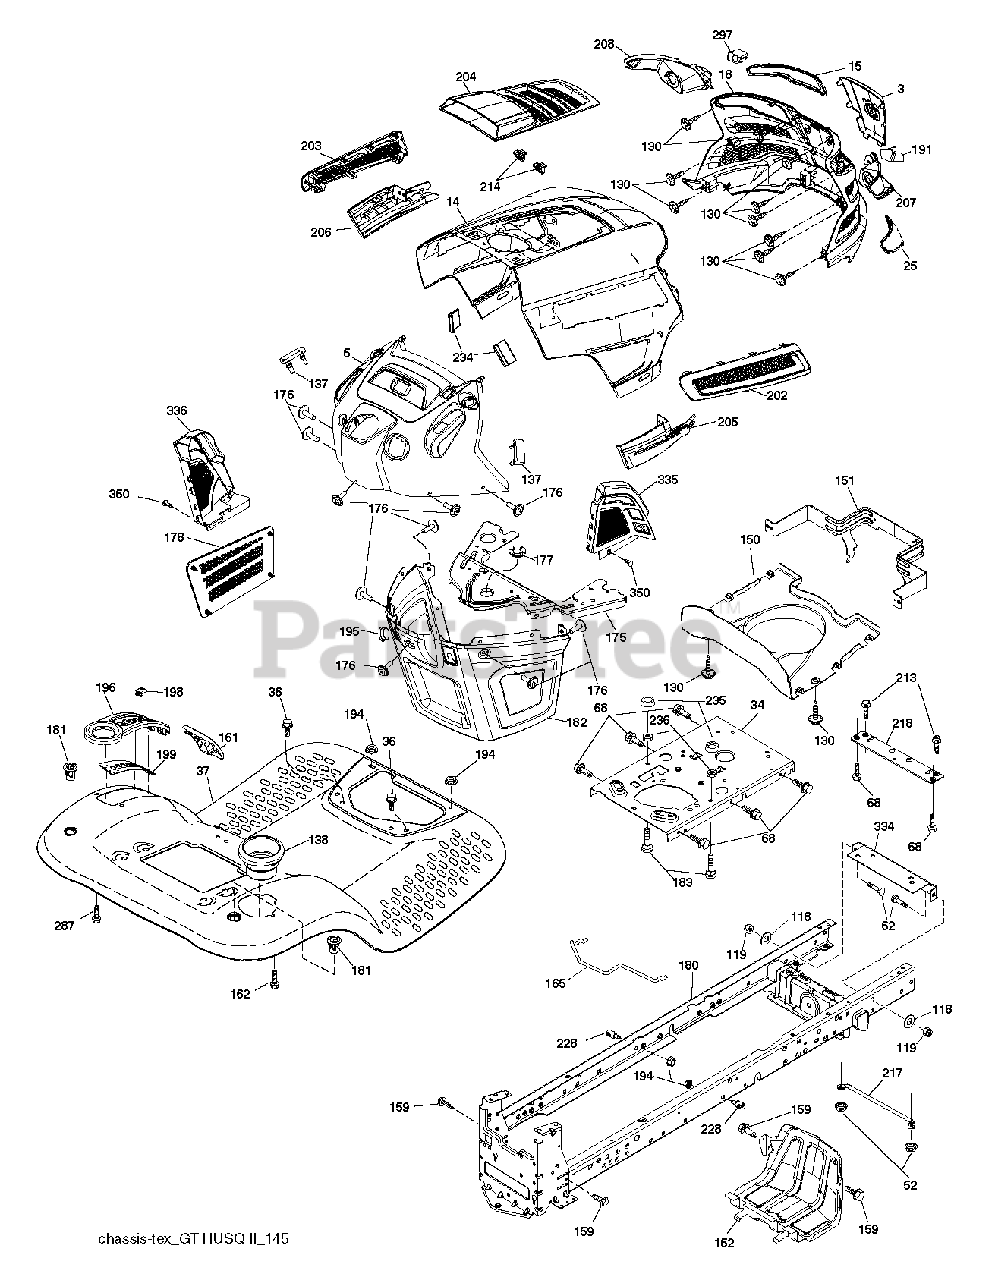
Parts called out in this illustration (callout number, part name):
3	APPLIQUE.SUBASM.GT.HUSQ.II
5	DASH.UPPER.ASSY.GT2.GREY
14	HOOD.ASM.HUSQVARNA.GT.TEX.ORAN
15	LENS.HEADLIGHT.LH.GTII.2011
18	GRILLE.SUBSTRATE.2011.
25	LENS.HEADLIGHT.RH.GTII.2011
34	PLATE.ENGINE.WELDED.CHASSIS
36	SCREW 5/16"
37	FENDER.ERGO.LT.W/CPH.W/FW.ORNG
52	LOCKNUT
62	BOLT D
68	SCREW LT
118	WASHER
130	SCREW.#10 X 0.750.BOS
137	BUMPER DASH
138	HOLDER.CUP.LT.GREY
150	AIR.DUCT.GTV2(2.54"RING HEIGHT
151	BRACKET.PIVOT.HOOD.GT.HUSQ.II
152	SHIELD.BROWNING.PNT.GT.V2
159	SCREW, 3/8-16X3/4
161	WINDOW.FUEL.LT.HUSQ.TEX.498
162	SCREW.HI-LO.CONSOLE
165	SUPPORT.TANK.REAR.W/TEX
175	PLATE.CROSSMEMBER.HUSQ
176	SCREW.#10-24X5/8.RN.QU
177	BUSHING, STEERING
178	CARGO.ASM.NET.TXGT.W/C
180	CHASSIS
181	BUSHING.MNT.FEND.CRGO.TEX.49
182	DASH.LOWER.COMMON.12V.ADAPTOR
183	BOLT.5/16-18X1-1/4 FULL THD
191	INSERT.REFLECTIVE.RH.HUSQ.GTII
194	NUT LOCK HEX FLANGE 5/16-18
195	PLUG.HOLE.DASH.LOWER.12V.BLK
196	DECKLFT.CONSOL FULL ASSM GREY
198	INDICATOR.DECK.LIFT.RED
199	PLATE.DECK.LIFT.HUSQ.LT
202	VENT.SIDE.RH.GT.HUSQ.II.
203	VENT.SIDE.LH.GT.HUSQ.II.498
204	VENT.TOP.HUSQ.GT2
205	SIDE.TRIM.RH.GT.HUSQ.II
206	SIDE.TRIM.LH.GT.HUSQ.II.GRAY
207	BEZEL LIGHT.RH.GT.II.MYLAR
208	BEZEL LIGHT.LH.GT.II.MYLAR
213	BOLT
214	CLIP.RETAINER.TINNER.
217	ROD.PIVOT.HOOD
218	X-PIECE.HOOD.STOP.NON/
228	STUD.FASTNER.W/ANTI-ROTATE
234	BUMPER.HOOD.TEX.HUSQVARNA
235	SPACER FENDER
236	NUT.CENTERLOCK.5/16-
287	SCREW 1/4X20
297	INSERT.REFLECTIVE.LH.HUSQ.GTII
334	BRACKET.ENGINE
335	COVER.LOWER.DASH.RH.BLACK
336	COVER-LH.LOWER.DASH.GT2.BLACK
350	CLIP.X-MAS.TREE
